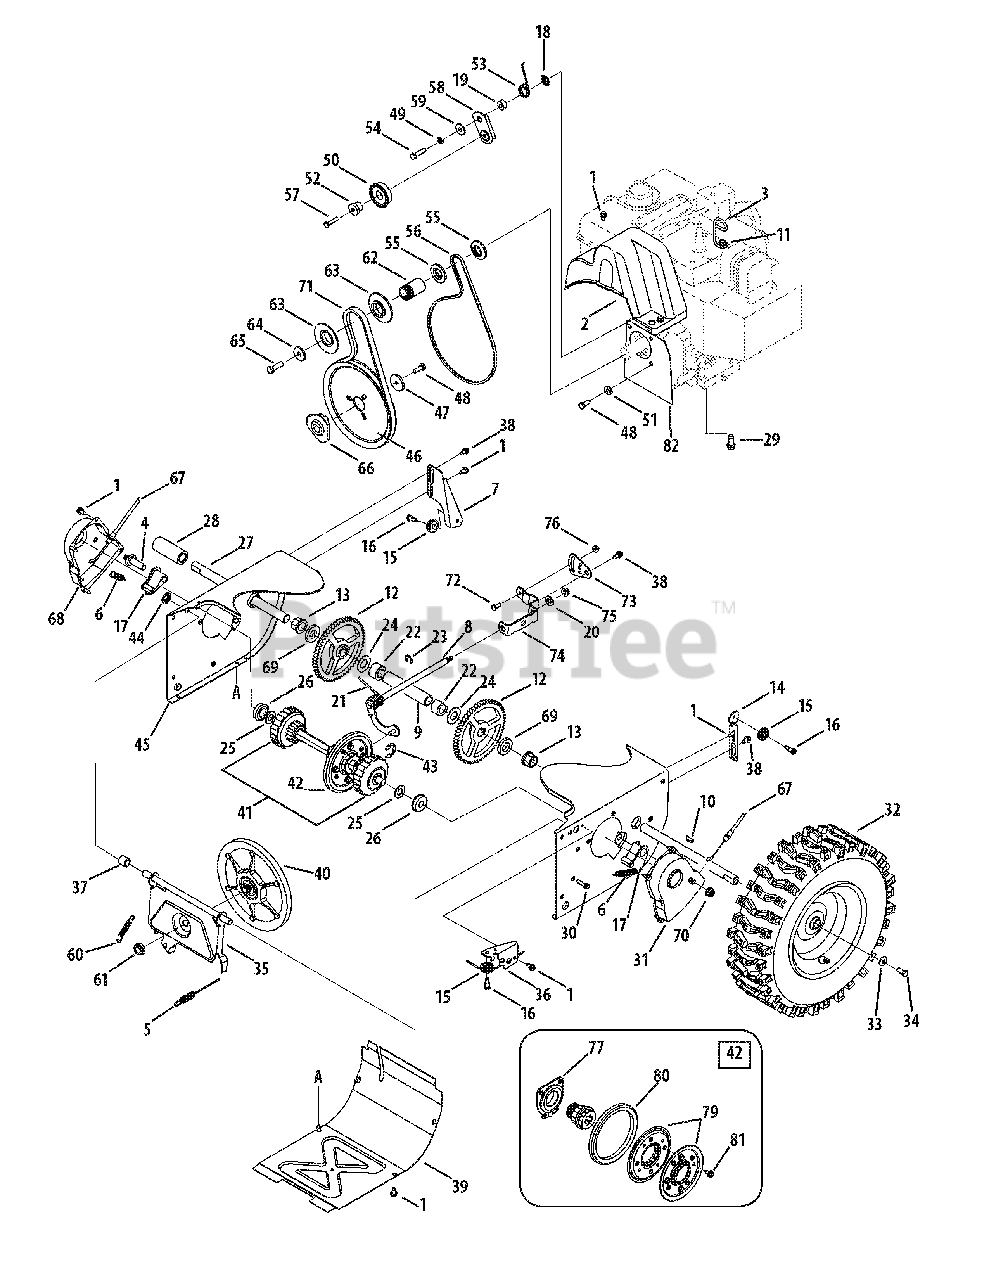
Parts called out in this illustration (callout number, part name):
1	AB Screw, 1/4-20 x 0.625
2	Belt Cover
3	Cable Guide
4	Actuator Shaft
5	Drive Clutch Cable
6	Extension Spring
7	Drive Clutch Cable Guide Bracket
8	Shift Rod Assembly
9	Axle Support Tube
10	Hi-pro Key
13	Hex Flange Bearing
14	Auger Clutch Cable Guide Bracket
15	Cable Roller
16	C Screw, 1/4-28 x 0.375
17	Dogg Assembly - LH
17	Dogg Assembly - RH
18	Speed nut
19	Spacer
20	Flat Washer, .469 x .875 x .105
21	Torsion Spring, .750ID x .968 Lg.
24	Flat Washer, .76 x 1.49 x .06
25	Flat Washer
26	Ball Bearing
29	TT Sems Screw, 3/8-16 x 1.0
30	TT Screw, 1/4-20 x 1.0
31	Shaft Retainer - LH
32	Wheel Complete - LH (16 x 6.5 x 8); 28"
32	Wheel Complete - RH (16 x 6.5 x 8); 28"
32	Wheel Complete - LH (15x5x6); 24"
32	Wheel Complete - RH (15x5x6); 24"
33	Bell Washer
34	Hex Bolt, 5/16-24 x .75
35	Friction Wheel Support Brkt. Assy.
36	Auger Cable Guide Bracket
38	Shoulder Screw
40	Friction Wheel Disc Assembly
41	Drive Shaft Assembly
42	Friction Wheel Assembly
43	Retainer Ring
44	Speed Nut
45	Wheel Drive Frame
46	Auger Pulley
47	Flat Washer
48	Hex Bolt, 5/16-24 x 0.875
49	Lock Washer
50	Pulley Assembly
51	Shoulder Spacer
53	Torsion Spring
54	Hex Screw, 5/16-24 x 1.25
55	Pulley Half
56	V-Belt, 3/8 x 34
57	TT Screw, 1/4-20 x 1.25
58	Drive Clutch Idler Bracket
59	Shoulder Spacer
60	Extension Spring
61	Flange Nut, 5/8-18
63	Pulley Half
64	Flat Washer
65	Hex Bolt, 3/8-24 x 1.25
66	Pulley Adapter
67	Steering Cable
68	Shaft Retainer - RH
69	Axle Spacer
70	Flange Lock Nut, 3/8-16
71	V-Belt,.500 x 35.00 Lg
72	Hex Screw, 1/4-20 x .620
73	Speed Selector Pivot Bracket
74	Speed Selector Shift Bracket
75	Flange Lock Nut, 5/16-18
76	Flange Lock Nut, 1/4-20
77	Friction Wheel Bearing Assembly
79	Friction Wheel Plate
80	Friction Wheel Rubber
82	Cover Plate
